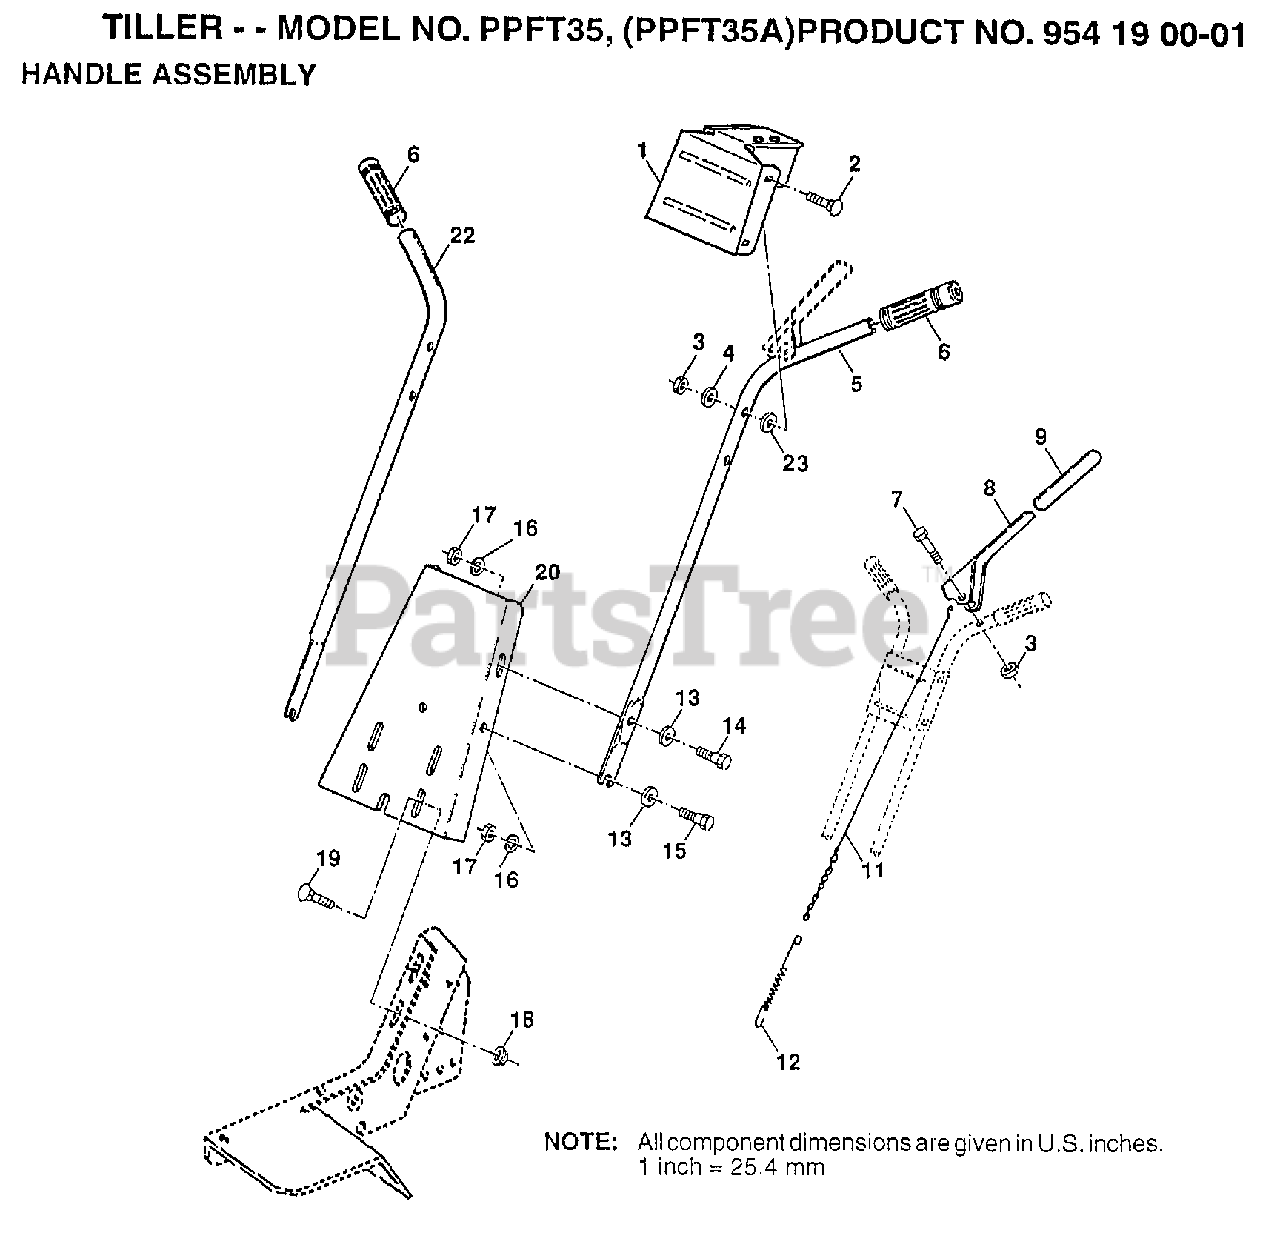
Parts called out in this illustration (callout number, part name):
2	BOLT, CARRIAGE
3	LOCKNUT, CROWN 5/16-18
4	WASHER 11/32 X 11/16 X 16 GA.
7	BOLT, HEX 5/16-18 X 1-1/2
13	WASHER 3/8 X 7/8 X 14 GA.
14	BOLT, HEX HD 5/16-18 X 1
15	BOLT, HEX 5/16-18 X 3/4
18	NUT, FLANGED
19	BOLT, CARRIAGE
23	WASHER
